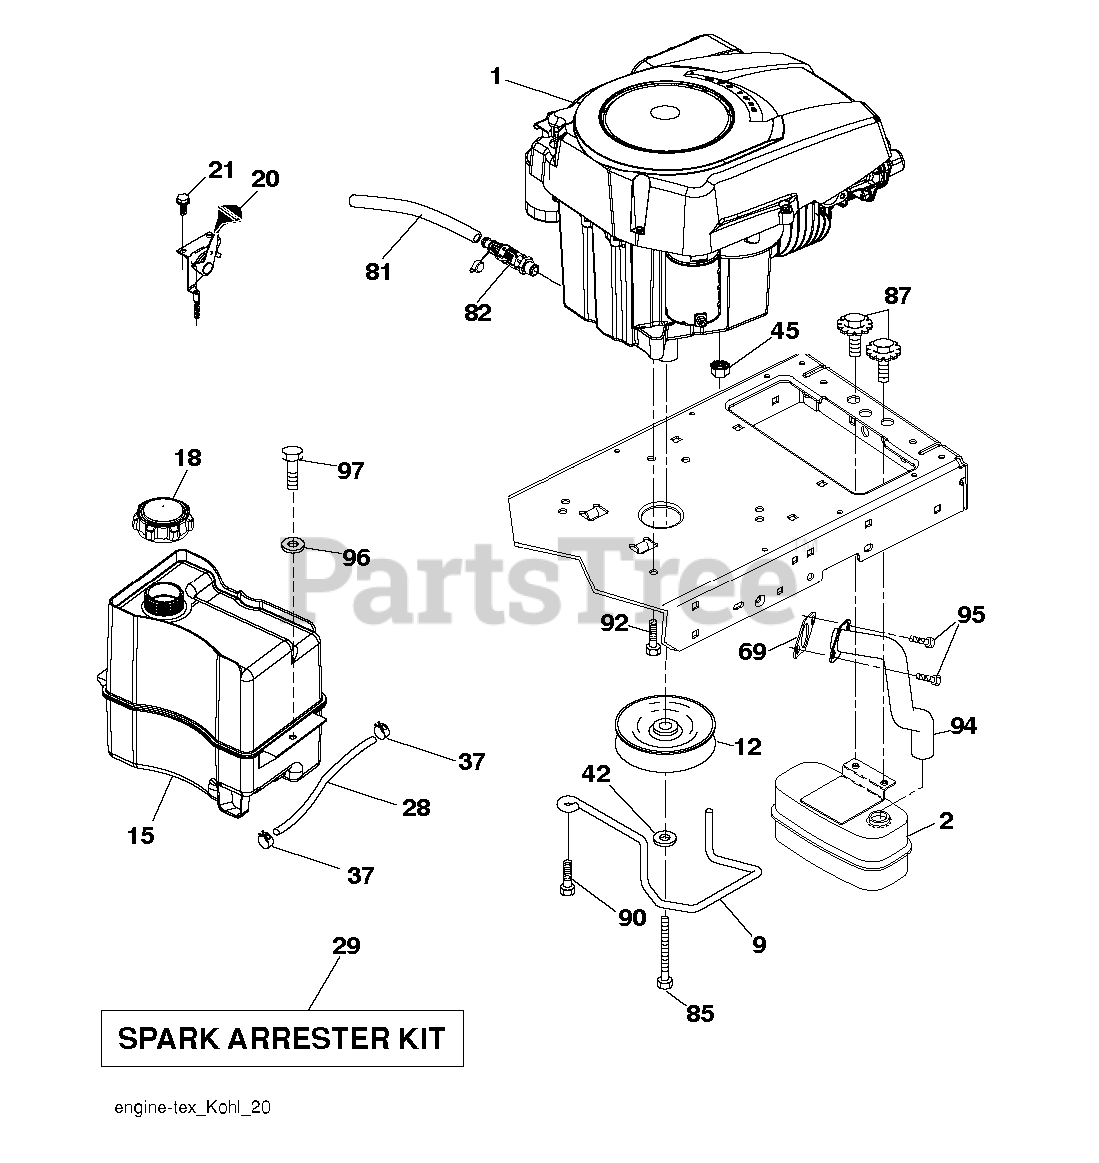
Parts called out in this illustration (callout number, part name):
2	MUFFLER.SINGLE.CYL.KOHL/B&S
9	KEEPER.BELT.ENGINE.4.2
12	RP_PULLEY ENGINE
15	TANK.ASM.FUEL.FR.2.5GA.
18	CAP ASM.FUEL.2.25"FR.
20	CONTROL.TH/CK.COBRA.KO
21	SCREW.#10 X 0.750.BOS
28	LINE.FUEL.20
29	KIT.SPARK ARRESTOR 794945 B&S
37	HOSE CLAMP
42	LOCKWASHER
45	NUT
69	GASKET.EXHAUST.KOHLER
81	TUBE, DRAIN OIL ASM.
82	VALUE.OIL.DRAIN
85	BOLT HEX 7/16-20X4-1/4"
87	BOLT 5/1618UNC X 3/4 W/ SEMS
90	SCREW 3/8-16X1
92	SCREW 3/8-16X1
94	RP.TUBE.EXHAUST.KOHL.COURAGE
95	SCREW.SOCKET HD.5/16-1
97	SCREW HEXWSHR 1/4-20X3/4
